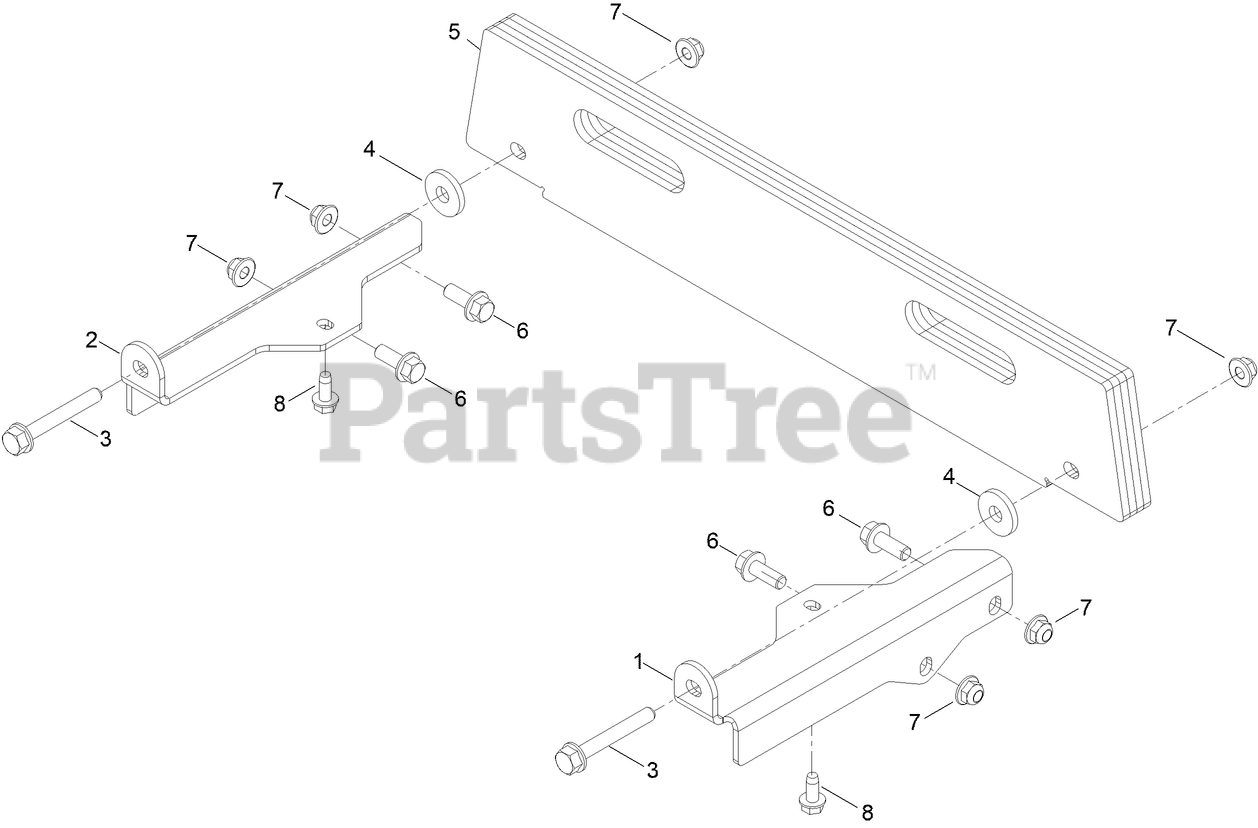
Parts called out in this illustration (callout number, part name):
1	BRACKET-WEIGHT TC [BLACK]
2	BRACKET-WEIGHT TC [BLACK]
3	SCREW-SPCL
4	WASHER
5	WEIGHT-BAGGER
6	SCREW-HHF
7	NUT-HF, NI
8	SCREW-HWHTF
